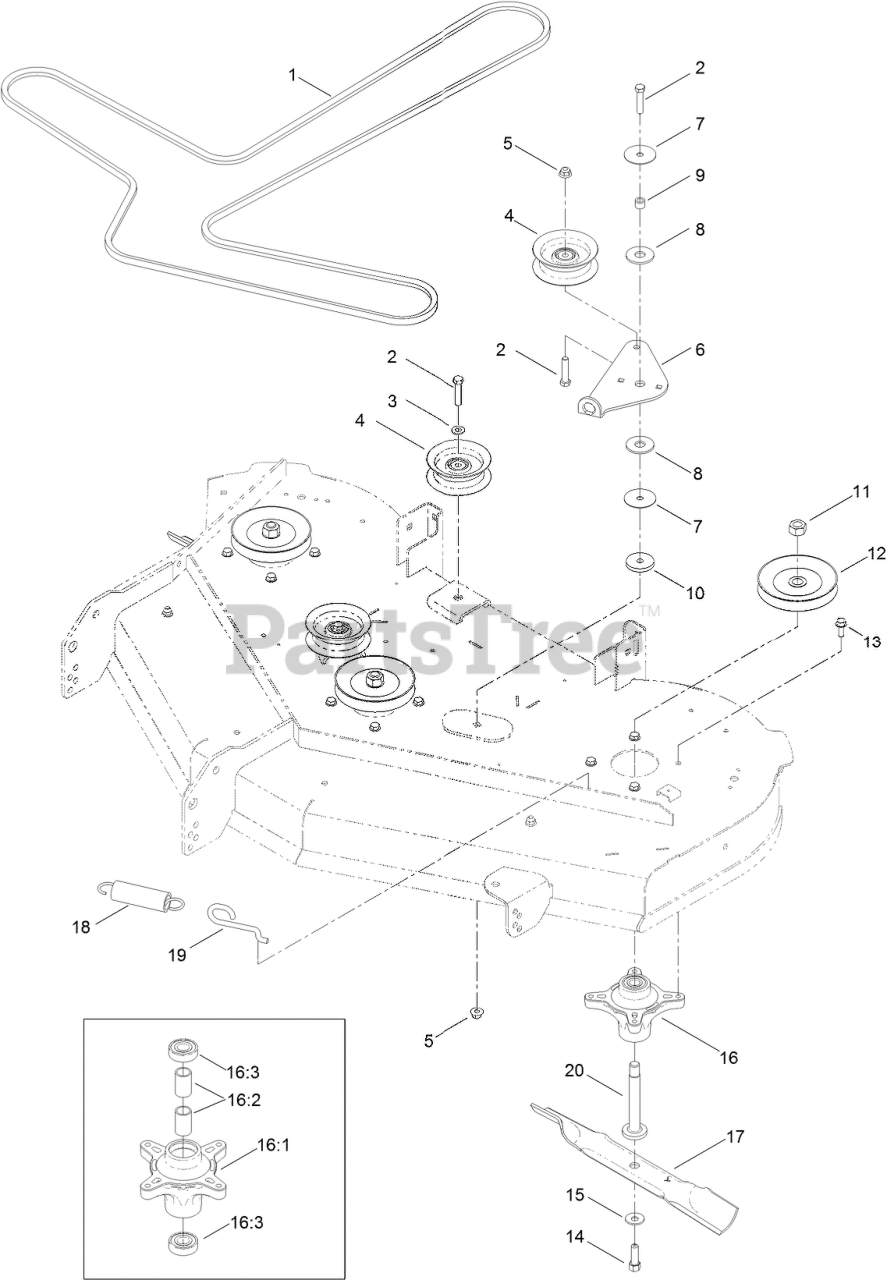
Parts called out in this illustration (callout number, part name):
1	V-BELT
2	SCREW-HH
3	WASHER-FLAT
4	PULLEY-IDLER, FLAT
5	NUT-HF, NI
6	ARM-IDLER
7	WASHER
8	WASHER-FRICTION, COMPOSITE
9	SPACER
10	SCREW-HH
11	NUT-HEX
12	PULLEY
13	SCREW-TAPTITE
14	SCREW-HH
15	WASHER-BELLEVILLE
16	SPINDLE ASM
16:1	SPINDLE
16:2	SPACER
16:3	BEARING-BALL
17	BLADE-HI LIFT
18	SPRING-EXTENSION
19	HOOK-RETURN, SPRING
20	SHAFT-SPINDLE
